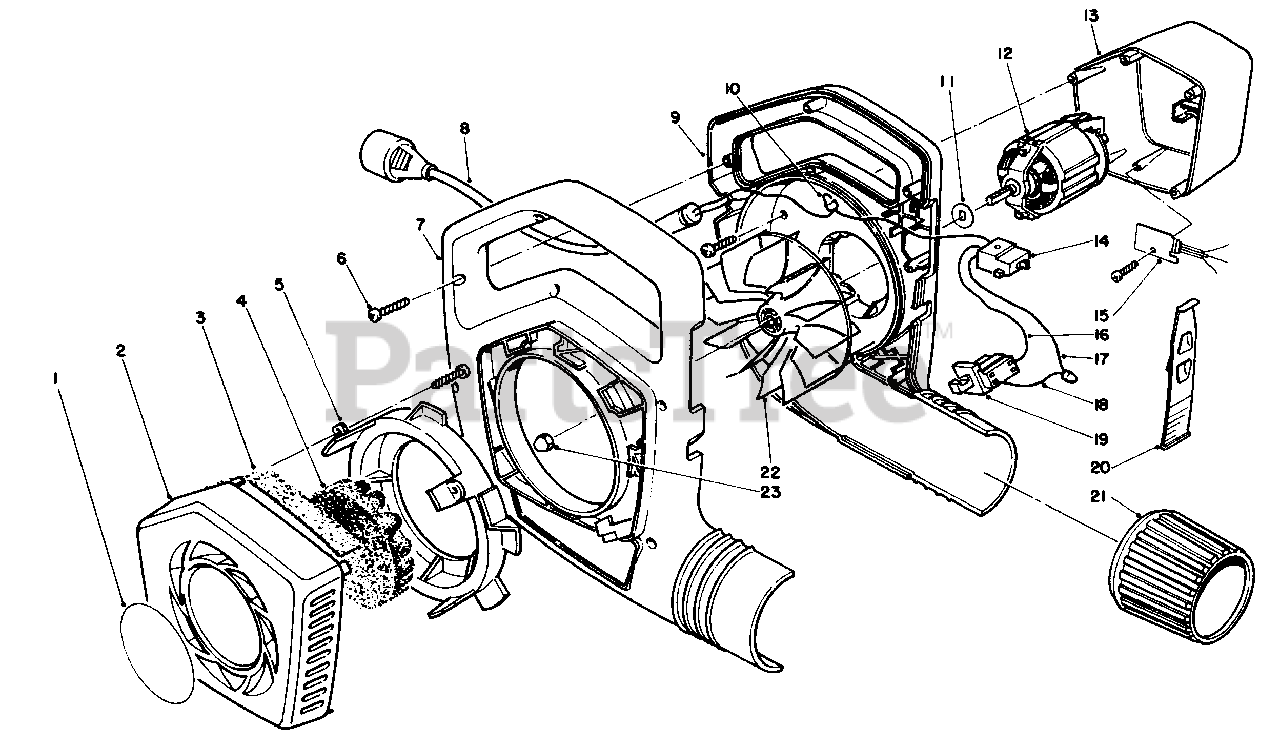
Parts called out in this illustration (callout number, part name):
1	Decal-Cover
2	Cover-Intake
3	Foam-Top
4	Foam-Center
5	Ring-Coupling
6	Screw-Self Tapping
7	Housing-Blower, R.H.
8	Cord-Power Supply
9	Housing-Blower, L.H.
10	Connector-Wire
11	Washer-Impeller
12	Motor-Blower
13	Cover-Motor
14	Switch-Varispeed
15	Speed Control Assembly
16	Wire-Internal
17	Wire-Internal, White
19	Switch-Interlock
20	Switch-Cam, Varispeed
21	Collar-Output
22	Impeller
23	Nut-Cap, Locking
